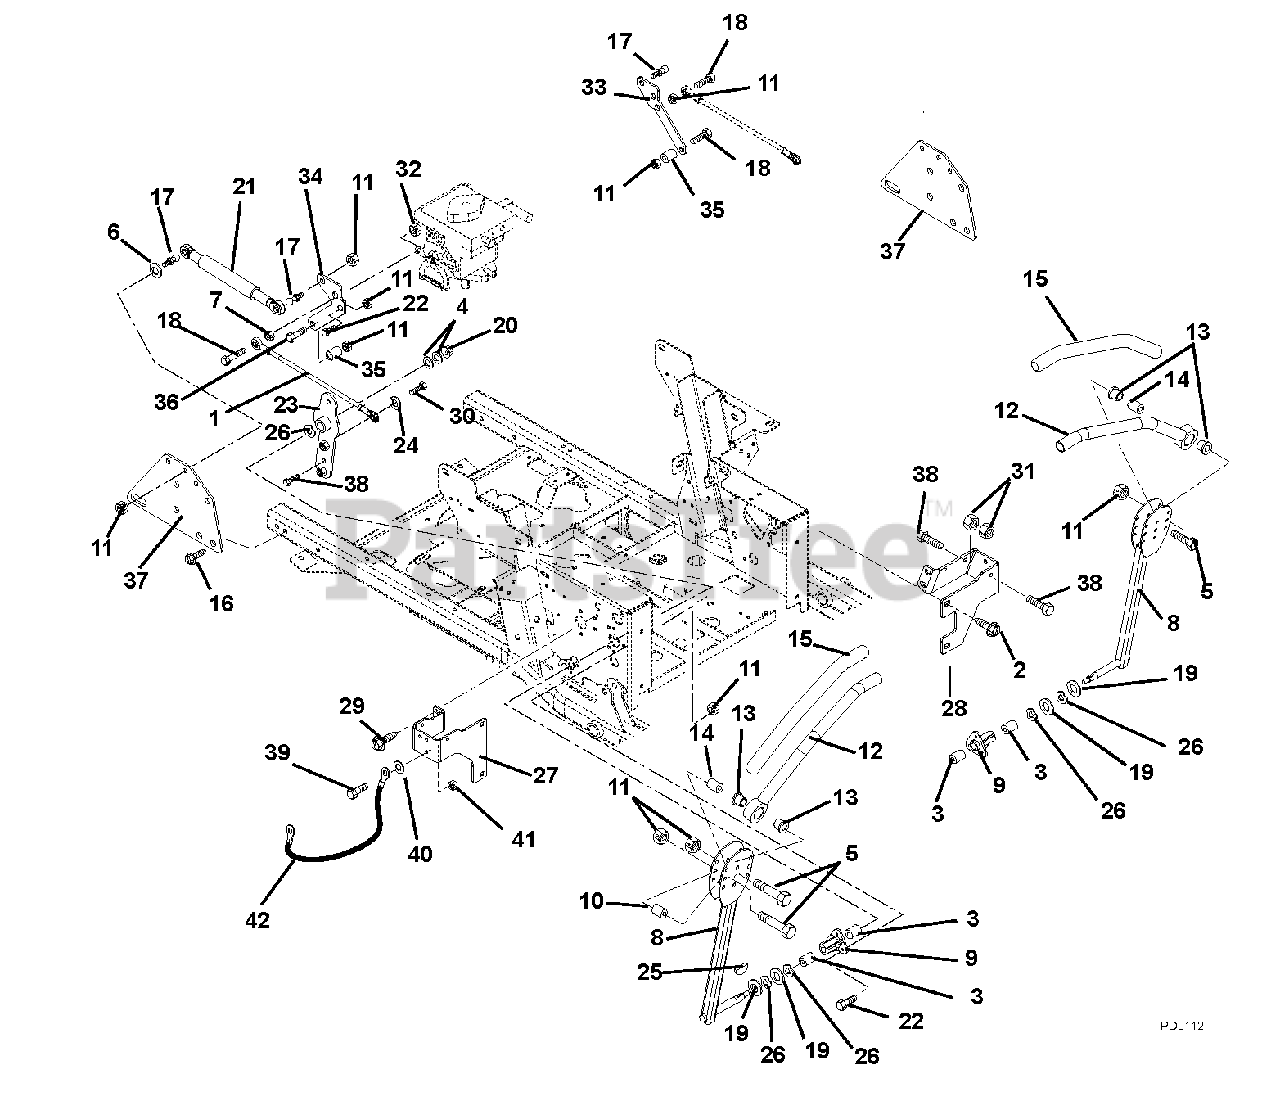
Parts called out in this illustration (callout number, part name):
1	Assembly, Steering Rod .38 Rod x 7.60
2	Screw, Tapping .38-16 x .75 Hex Washer Head
3	Bushing .625 x .75 x .50
4	Washer, Flat Steel .403 x .812 x .065
5	Bolt, Hex .31-18 x 1.75 Grade 5
6	Washer, Flat Steel .344 x .688 x .065
7	Nut, Hex .38-16
8	Control Arm
9	Bushing, Flange
10	Eccentric
11	Nut, Locking Top Flange .31-18
12	Handle Weldment Left-Hand
13	Bushing, Flange Nylon .762 x 1.48 x .44
15	Grip, Handlebar
16	Screw, Tapping .31-18 x .50 Hex Washer Head
17	Stud, Ball
18	Bolt, Hex .38-16 x 1.50 Grade 5
19	Washer, Flat Steel .63 x 1.005 x .062
20	Nut, Locking Top Flange .38-16
21	Damper, Control
22	Bolt, Hex .31-18 x .75 Grade 5
23	Weldment, Pivot Arm
24	Washer, Locking .38 x .094 Regular
25	Key, Woodruff .13 x .63
26	Washer, Wave
27	Stop, Steering Right Hand
28	Stop, Steering Left Hand
29	Screw, Tapping .38-16 x .50 Hex Washer Head
30	Bolt, Hex .38-16 x 1.25 Grade 5
31	Nut, Hex Jam .375-16
32	Nut, Locking Center .38-16
33	Bracket, Left Hand (992148, 149, 150, 151, 152, 153, 154, 155, 157, 159)
34	Bracket, Right Hand (992148, 149, 150, 151, 152, 153, 154, 155, 157, 159)
35	Spacer .318 x .43 x .375
36	Bolt, Hex .31-18 x 1.25 Grade 5
37	Bracket, Damper
38	Bolt-Hex .375-16 x 1.75 Full Thread
39	Bolt-Hex .25-20 x .75 Grade 5
40	Washer, Flat Steel .265 x .50 x .087
41	Nut, Locking Top Flange .25-20
42	Cable, Hood
